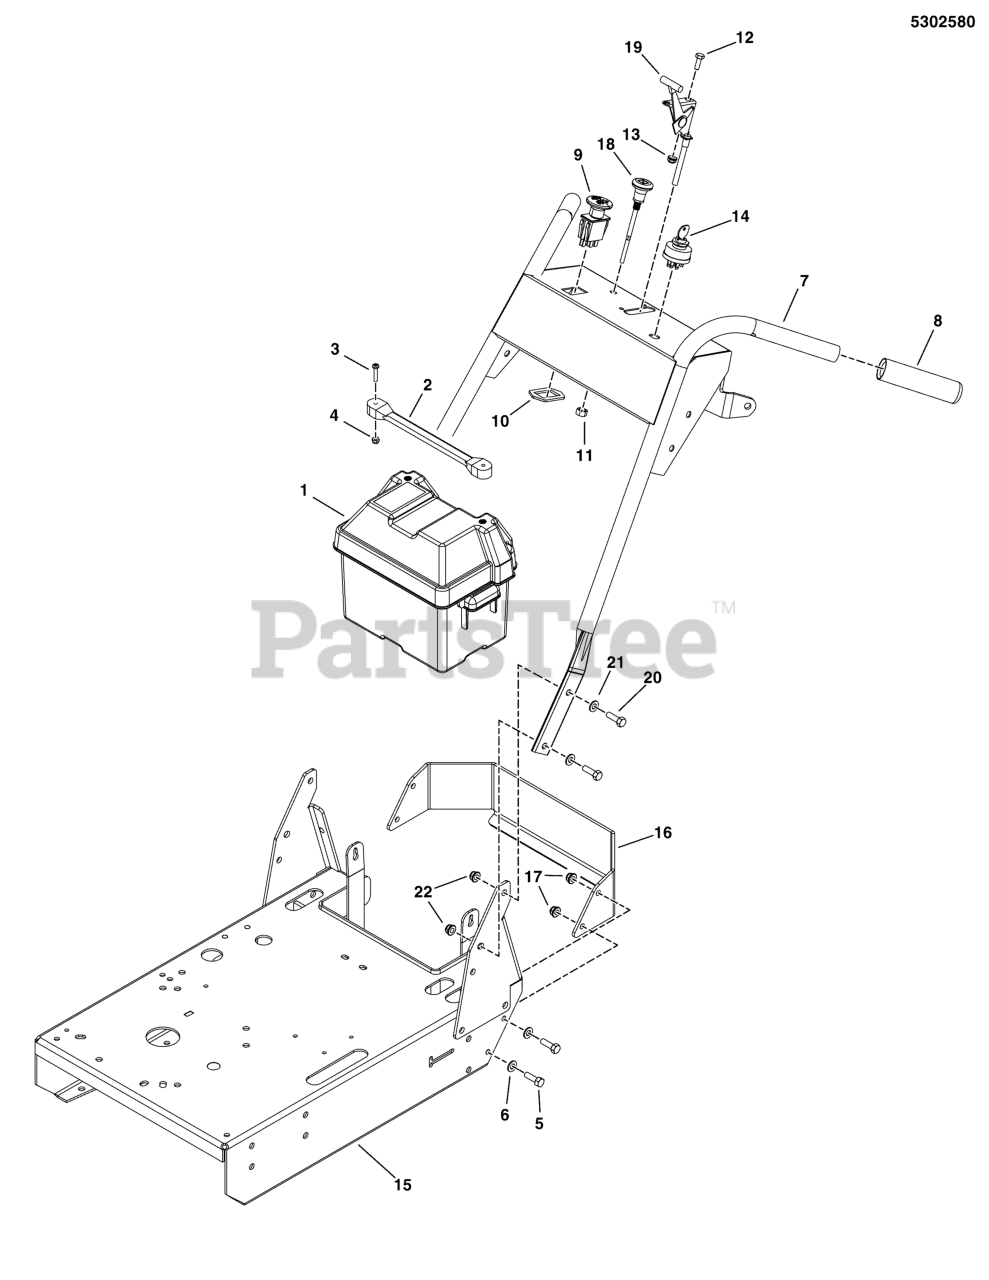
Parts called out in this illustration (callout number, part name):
1	BATTERY BOX, W/ DRAIN HOLE
2	STRAP, RUBBER
3	SCREW, #10-24 X 1 RS, CZ
4	NUT, #10-24 HEX NYLON LOCK
5	BOLT, 5/16-18 X 1 GD5 YZ
6	WASHER, 5/16" SAE
7	WELD, HANDLE BAR, TD - RED
8	GRIP, FOAM, .940" X 4.62" X .187"
9	SWITCH, BLADE ENGAGEMENT
10	RING, SWITCH RETAINER
11	NUT, 3/8-24 HEX
12	BOLT, 1/4-20 X 3/4 GD5 YZ
13	NUT, 1/4-20 HEX NYLOCK FLANGE
14	SWITCH, IGNITION, 6 POST
15	WELD, ENGINE DECK, HYDROCUT - RED
16	PLATE, BUMPER, HYDROCUT - RED
17	NUT, 5/16-18 HEX NYLOCK FLANGE
18	CABLE, CHOKE CONTROL, 43.5"
19	CABLE, THROTTLE CONTROL, 40"
20	BOLT, 3/8-16 X 1-1/4" GD5 CZ
21	WASHER, 3/8 SAE
22	NUT, 3/8-16 HEX NYLOCK FLANGE
